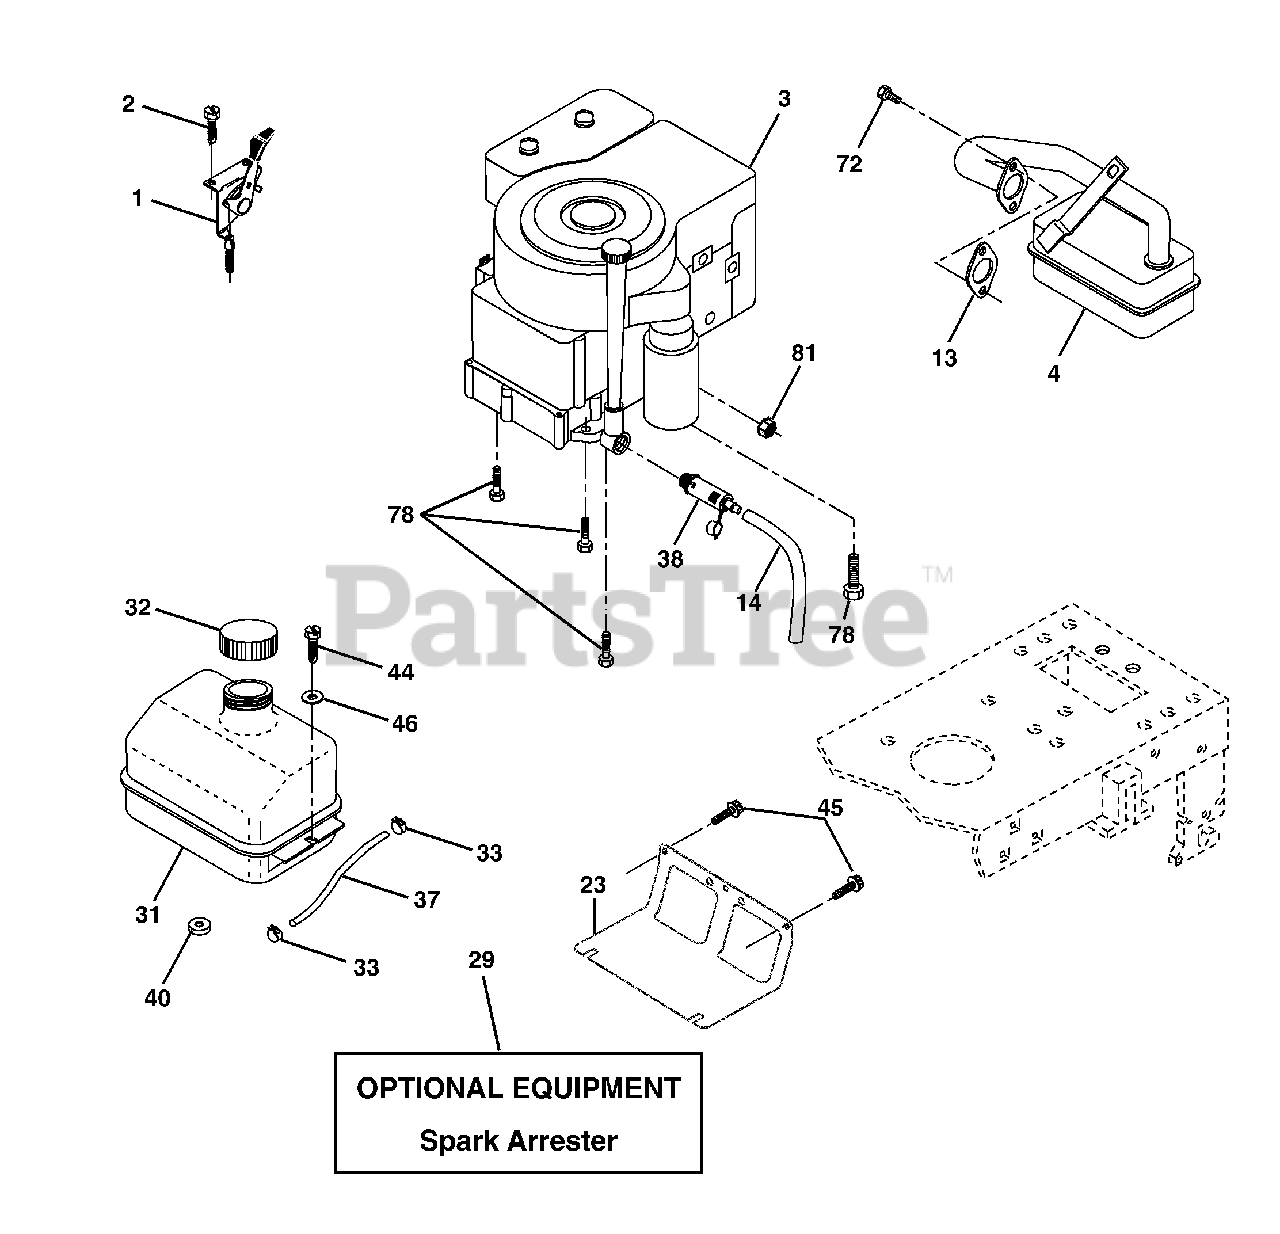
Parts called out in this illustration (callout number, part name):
1	Control Th/ch Flag
2	Screw Hex Thd Cut 1/4-20 x 1/2
4	Muffler Exhaust B&S
13	Gasket Eng 1 313 Id Tin Plated
14	Tube Drain Oil Easy
23	Shield BRN/DBR Guard
29	Kit Spark Arrestor (Flat Scrn)
31	Tank Fuel Front
32	Cap Asm Fuel
33	Clamp Hose
37	Line Fuel 20"
38	Plug Drain Oil
40	Bushing Snap Nyl Blk Fuel Line
44	Screw Thdrol 1/4-20 x 3/4
45	Screw Hex Wsh Thdrol 3/8-16
46	Washer 9/32 x 7/8 x 16 Ga.
72	Screw Scocket Head 5/16-18 x 1
78	Screw 3/8-16 x 1-1/4
81	Nut Keps Hex 1/4-20 unc
